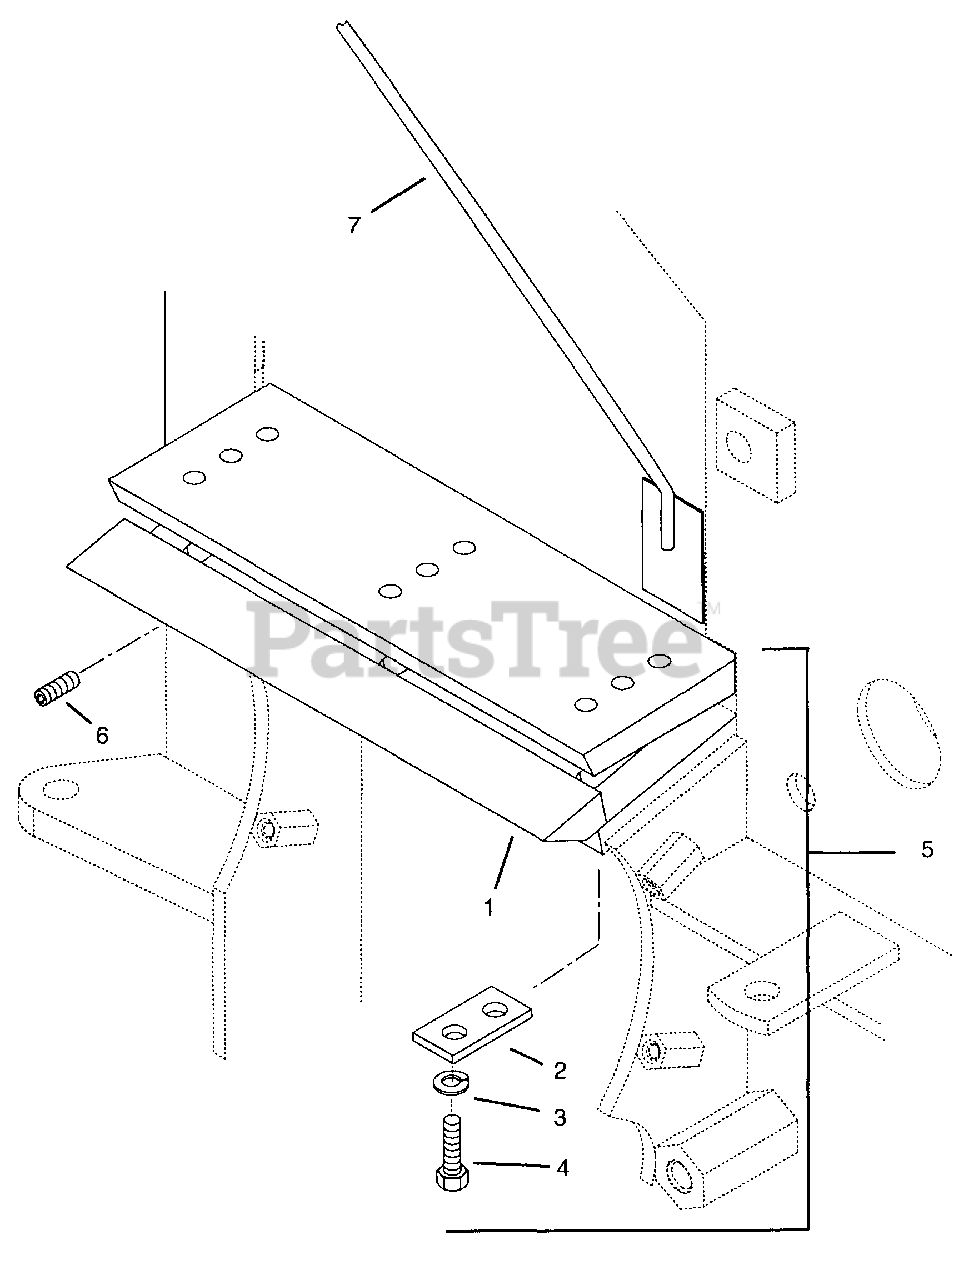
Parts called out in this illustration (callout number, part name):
2	Double Hole Washer
3	Washer-Locking .38 X .094
4	Bolt-Hex .38-24 x 1.25 Grade 8
5	Bed Knife Kit
6	Screw-Set-Socket Head .38-16 X .75
7	Knife Gauge .030
